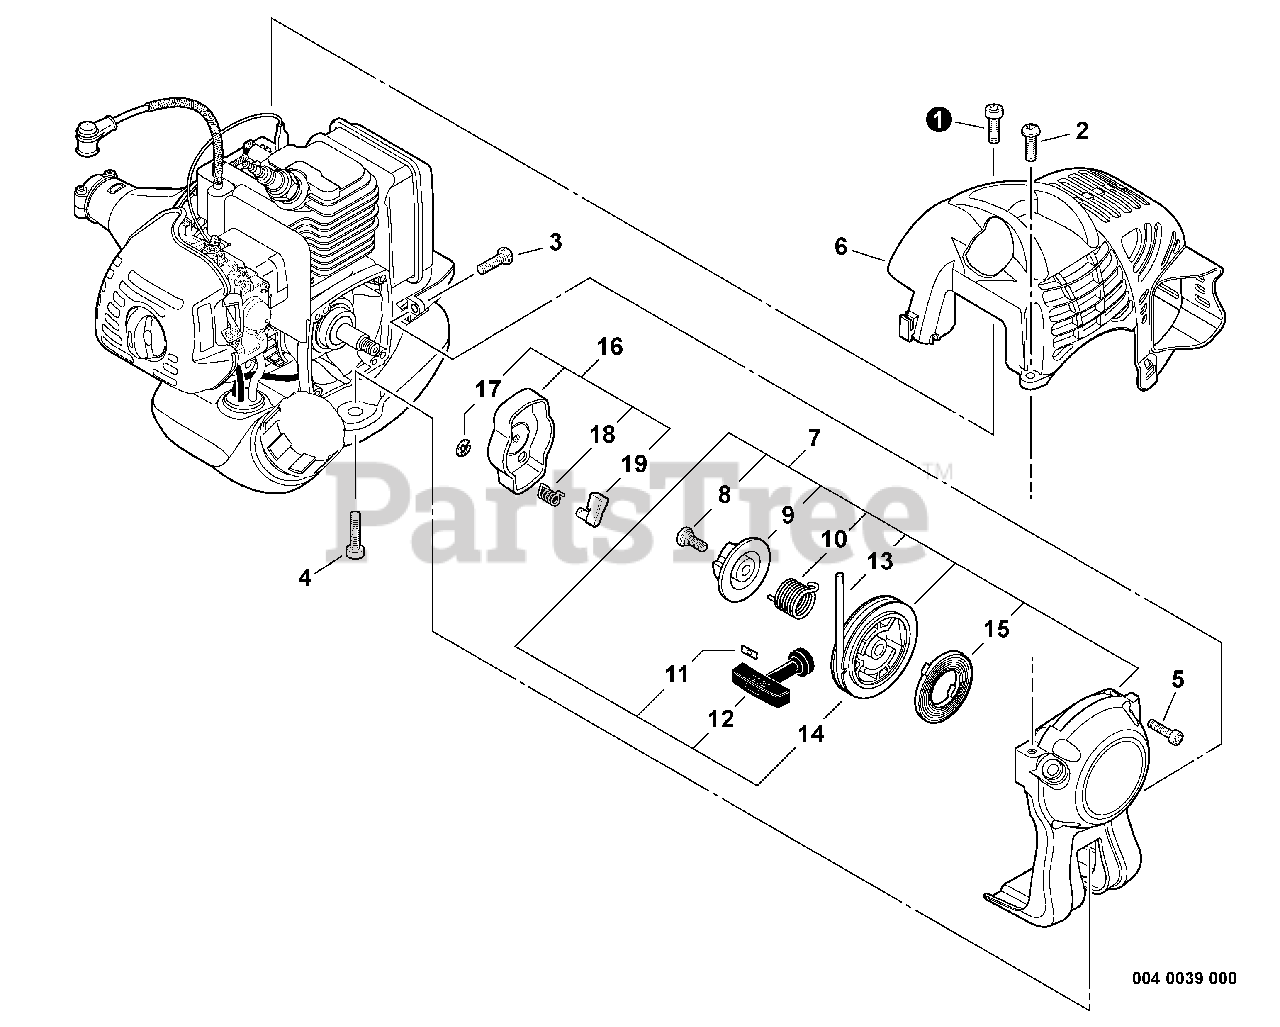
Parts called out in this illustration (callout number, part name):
1	SCREW - 5X16
2	SCREW - 5X16
3	SCREW - 5X16
4	SCREW - 5X20
5	SCREW - 4X16
6	COVER, ENGINE
7	STARTER ASSY
8	SCREW
9	PLATE, CAM
10	SPRING, DAMPER
11	RETAINER, ROPE
12	GRIP, STARTER
13	ROPE, STARTER - 3X700
14	REEL, ROPE
15	SPRING, REWIND
16	STARTER PAWL ASSY
17	RING, RETAINING - 4
18	SPRING, RETURN
19	PAWL, STARTER
